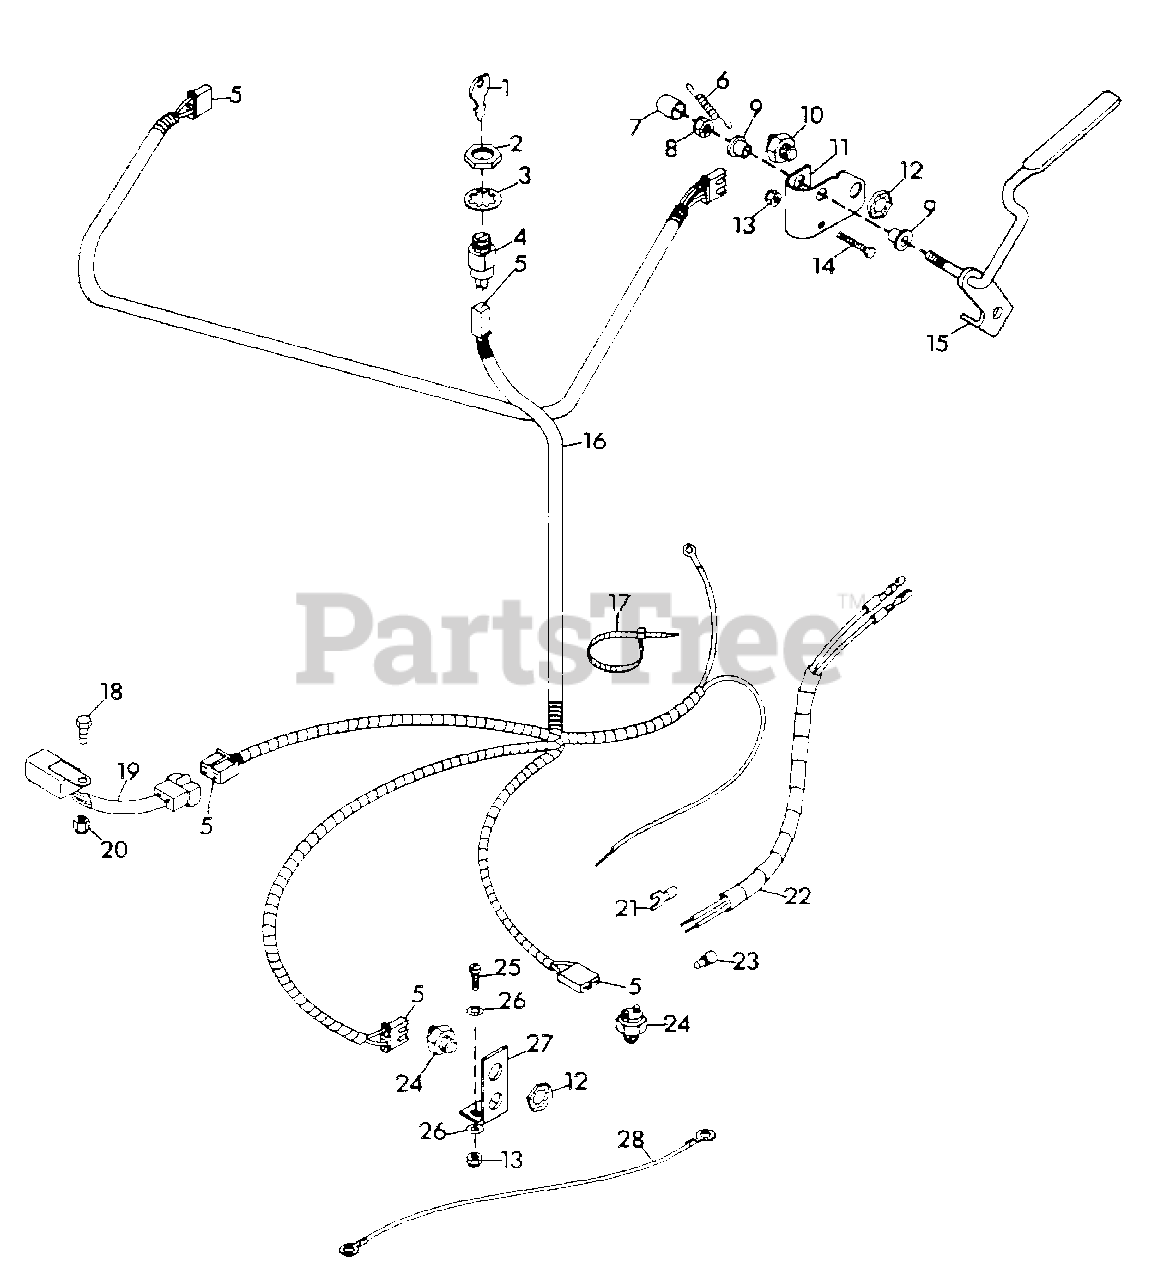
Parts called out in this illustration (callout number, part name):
1	KEY, IGNITION SWITCH
2	NUT, JAM 5/8-32
3	WASHER, LOCK 5/8 INT. TOOTH
4	SWITCH
5	TERMINAL
6	SPRING, INTERLOCK LEVER
7	CLOSURE, VINYL
8	NUT, LOCK 5/16-18
9	BUSHING, INTERLOCK LEVER
10	SWITCH, INTERLOCK
11	BRACKET, INTERLOCK ACTUATING
12	NUT, STAMPED 9/16-18
13	NUT, LOCK 10-24
14	SCREW, MACH. 10-24X1.50 PHD
15	LEVER, PRESENCE CONTROL
16	HARNESS
17	TIE, CABLE
18	BOLT, HEX 1/4-20X.625
19	MODULE, INTERLOCK RECOIL
20	NUT, LOCK 1/4-20
22	WIRE, ENGINE KILL
23	NUT, WIRE
24	SWITCH, NEUTRAL START
25	SCREW, MACHINE 10-24X.75 PHD
26	WASHER, FLAT .188X.438X.049
27	BRACKET, INTERLOCK SWITCH
28	WIRE, GROUND
